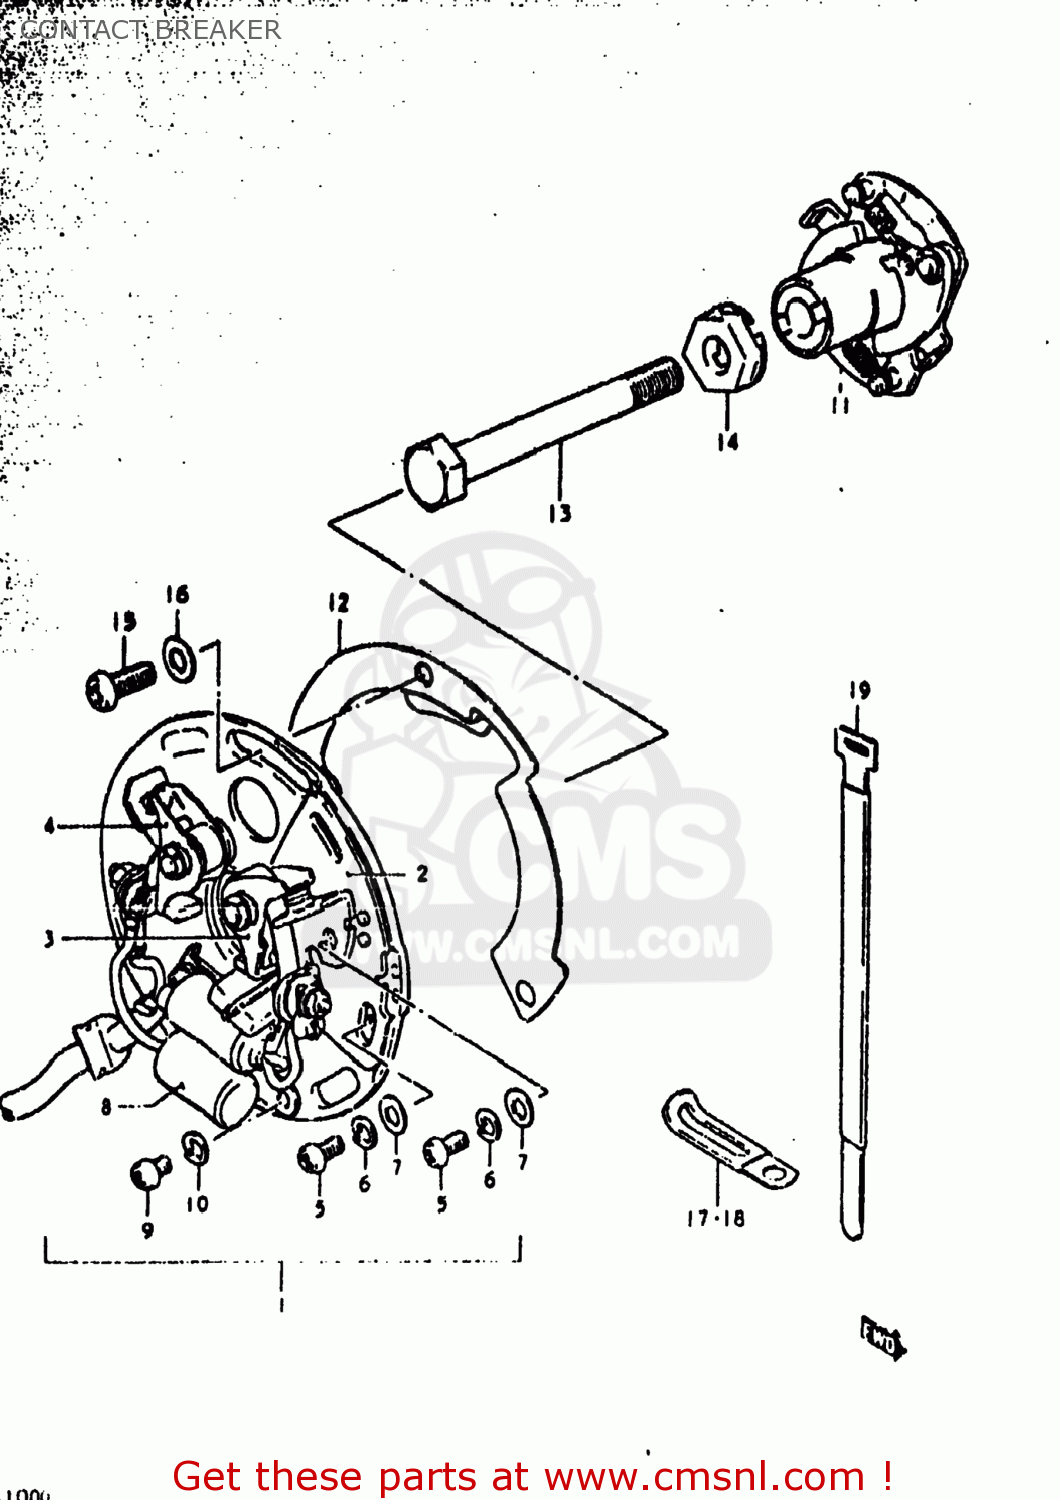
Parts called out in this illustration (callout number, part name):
1	BREAKER ASSEMBLY,CONTACT
2	PLATE,CONTACT POINT
3	POINT ASSY,R
4	POINT ASSY,L
5	SCREW(4X10)
6	LOCK WASHER
7	WASHER
8	CONDENSER
9	SCREW
10	LOCK WASHER
11	GOVERNOR ASSEMBLY
12	PLATE,IGNITION TIMING
13	BOLT
14	WASHER
15	SCREW(5X12)
16	WASHER 5MM
17	CLAMP L:35
18	CLAMP
19	CLAMP
